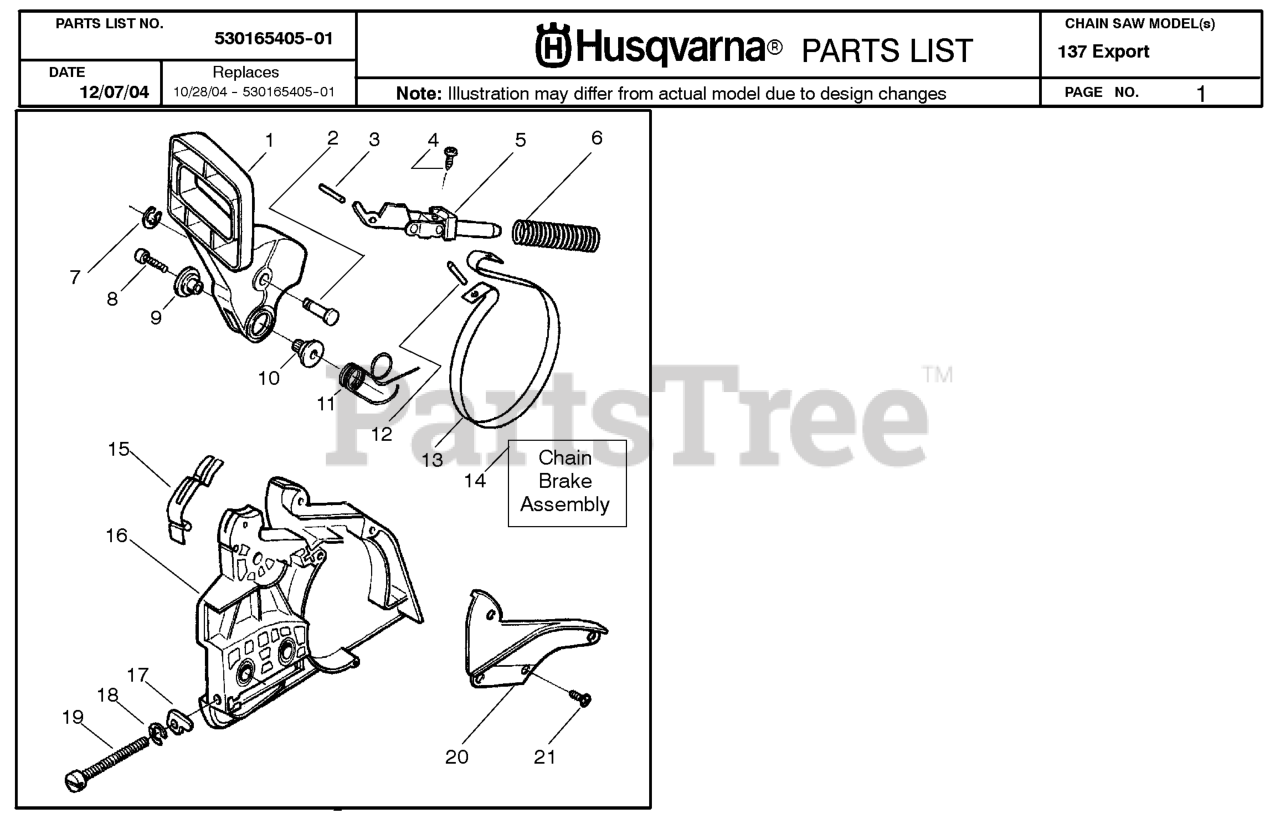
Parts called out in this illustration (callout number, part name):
4	SCREW
5	FRONT LINK ASSY
6	%COMPRESSION SPRING
9	JOURNAL, RIGHT
10	SHAFT PIVOT
11	SPRING,BRK HDL 36/41
13	BRAKE BAND
14	CHAIN BRAKE ASM.
15	SPRING-POSITION
16	CLUTCH COVER
17	ADJUST PIN,BAR 36/41
19	BAR ADJUSTING SCREW
20	CHAIN BRAKE COVER
21	SCREW
